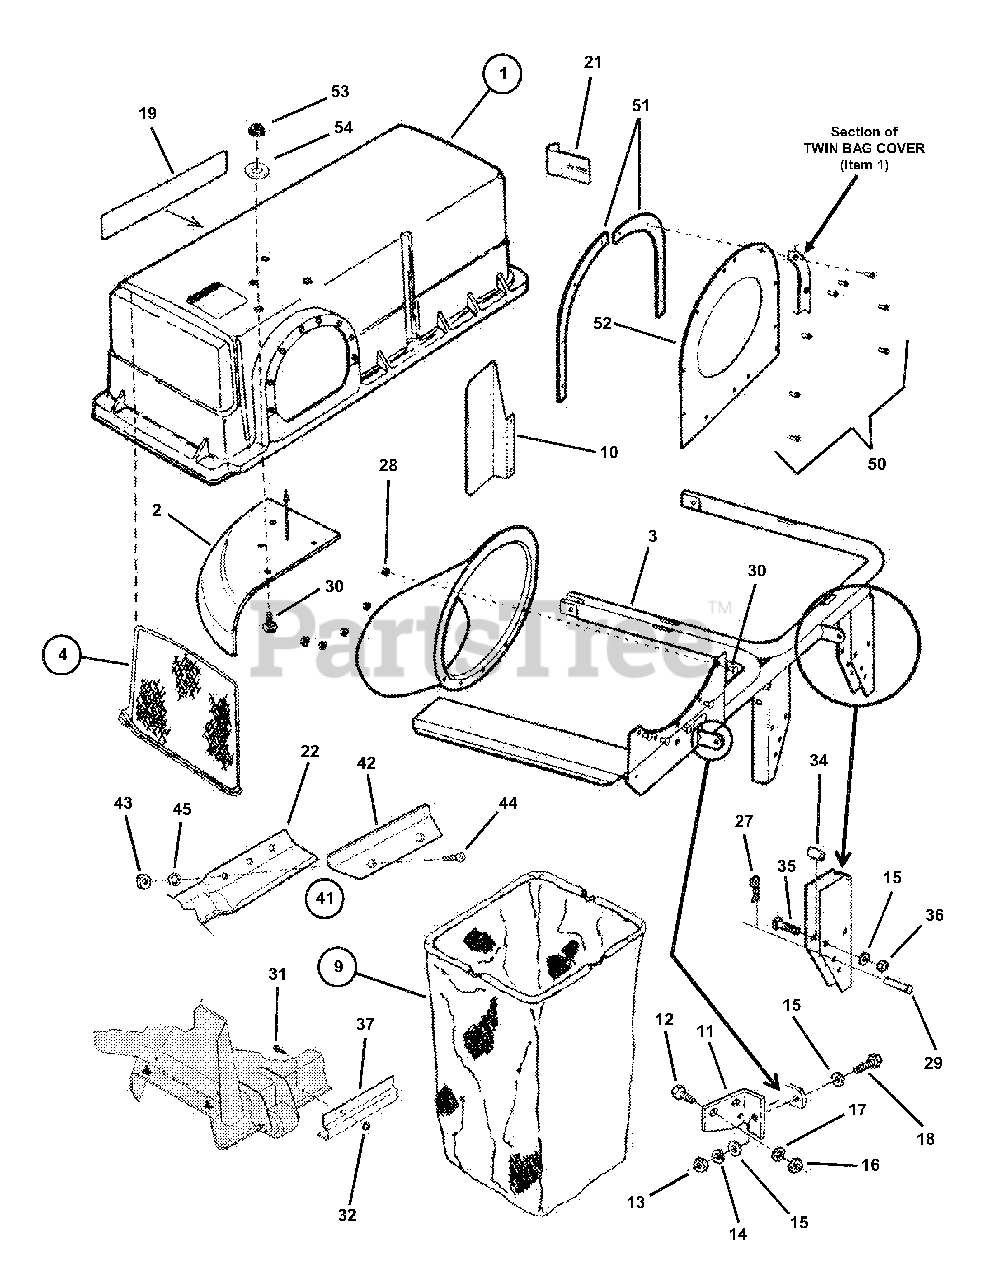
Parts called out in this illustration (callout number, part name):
1	ASS'Y, Cover
2	SECTOR
3	WELDMENT, Frame
4	ASS'Y, Screen (indented items)
9	ASS'Y, Bag (indented items)
10	GUARD, Muffler
11	HINGE, Top
12	SCREW, 1/4-28 x 3/4"
13	NUT, 5/16-24 Hex Center Lock
14	WASHER, 5/16" Split
15	WASHER, 5/16" Flat
16	NUT, 1/4-28 Hex
17	WASHER, 1/4" Internal Tooth Lock
18	SCREW, 5/16-24 x 1" Cap
19	DECAL, Snapper
21	SUPPORT, Bumper
22	BLADE, 21" Air Lift
27	PIN, 3/32 x 1-1/2" Hair
28	NUT, 1/4-20 Hex Flange Lock
29	PIN, 5/16 x 1-11/16" Clevis
30	BOLT, 1/4-20 x 1/2" Carriage
31	SCREW, 5/16-18 x 3/4" Carr.
32	NUT, 5/16-18 Hex Flge. Lock
34	PAD, Bumper Mount
35	BOLT, 5/16-18 x 1-1/2" Carr.
36	NUT, 5/16-18 Hex Ctr. Lock
41	KIT, Air Lift
42	AIR LIFT
43	NUT, 5/16-24 Hex
44	SCREW, 5/16-24 x 21/32"
45	WASHER, 5/16" Internal Tooth Lock
50	SCREW, #10-24 x 1/2" S.Tap
52	SEAL
53	NUT, 1/4-20 Hex
54	WASHER, 1/4" Flat
